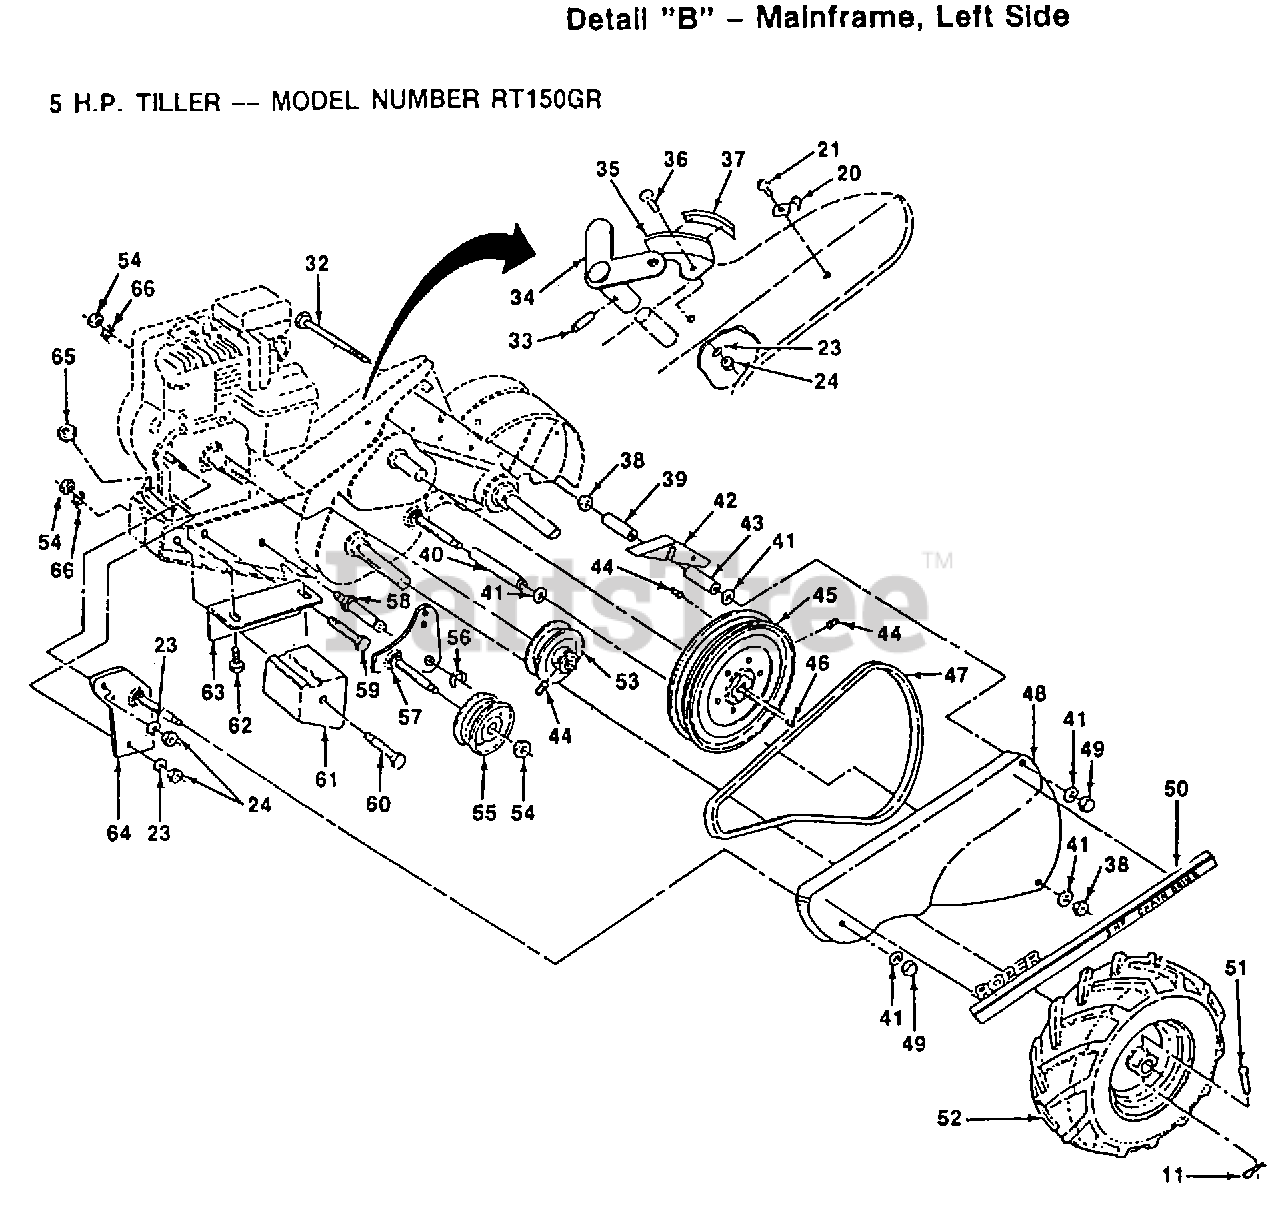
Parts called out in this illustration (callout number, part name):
11	RETAINER M
20	CONDIUT CLIP T
23	LOCKWASHER
32	BOLT-HEX TI
34	LEVER ASM CRT
35	PANEL TI
36	BOLT
38	NUT.HEX.5/16-18
39	SPACER CRT
40	SPACER
41	WASHER
42	GUARD CRT
43	SPACER CRT
44	SET SCREW
45	"SHEAVE 10"" CRT"
46	KEY T
49	NUT TI
54	NUT.HEX.3/8-16UNC
55	PULLEY-IDLER TI
56	KLIP RING
58	SHIFT ARM CRT
59	BOLT
60	BOLT CRT
61	COUNTERWEIGHT CRT
62	BOLT.HEX.5/16-1.5
63	BRACKET LH CRT
64	BRACKET ASSY CRT
66	LOCKWASHER
